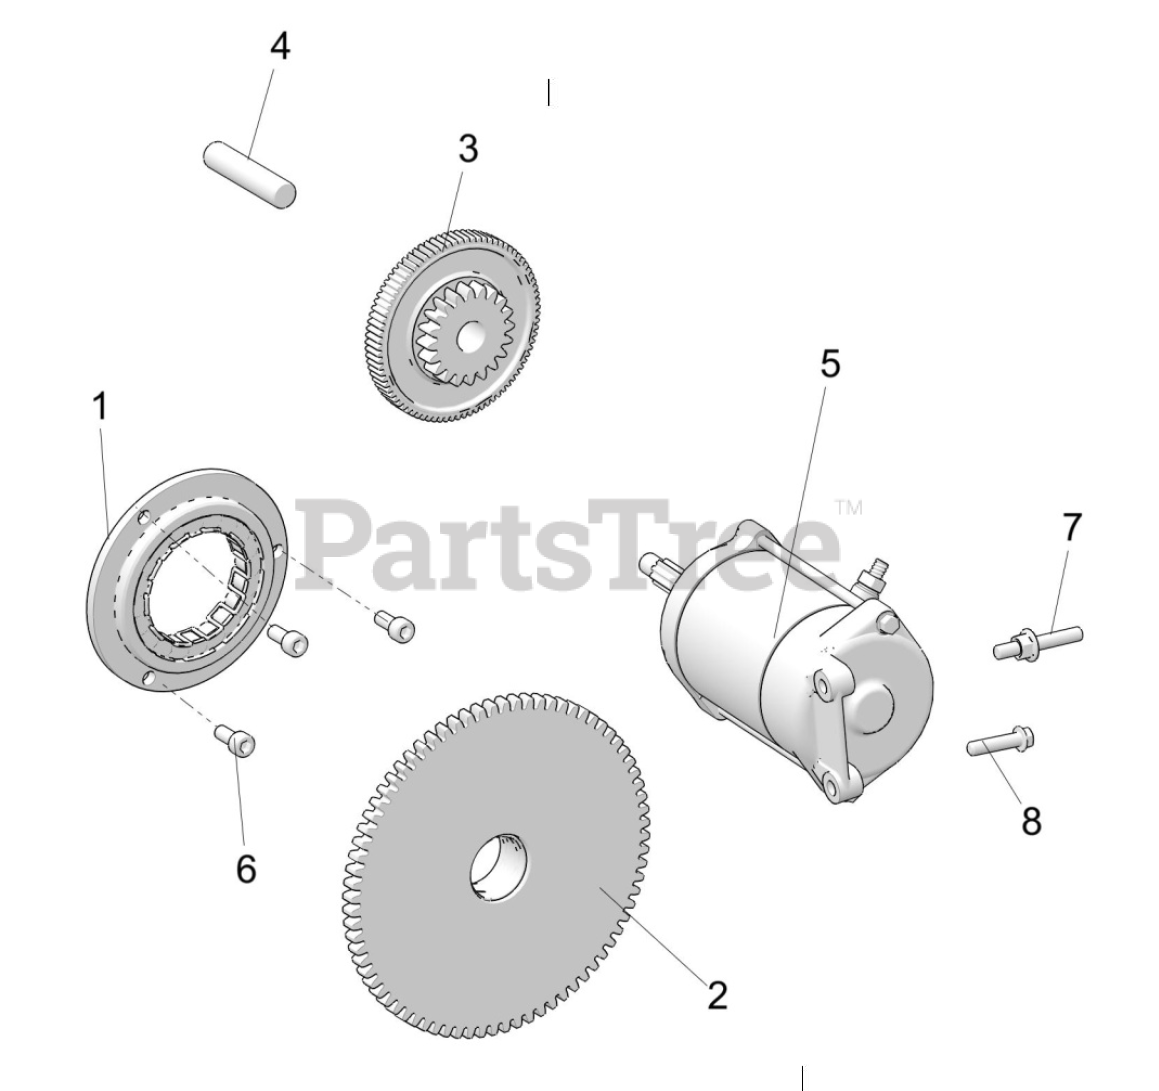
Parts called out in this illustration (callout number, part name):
1	ASM-SPRAG CLUTCH,HUB,STARTER
2	ASM., GEAR, STARTER , CRANK
3	ASM., TLG
4	PIN-TQ,LIMIT,GEAR
5	STARTER-9T,CW
7	STUD-DOUBLE,END,M6X1.0X25/10
8	SCR-HXFLG,M6X1.0X25,10.9
